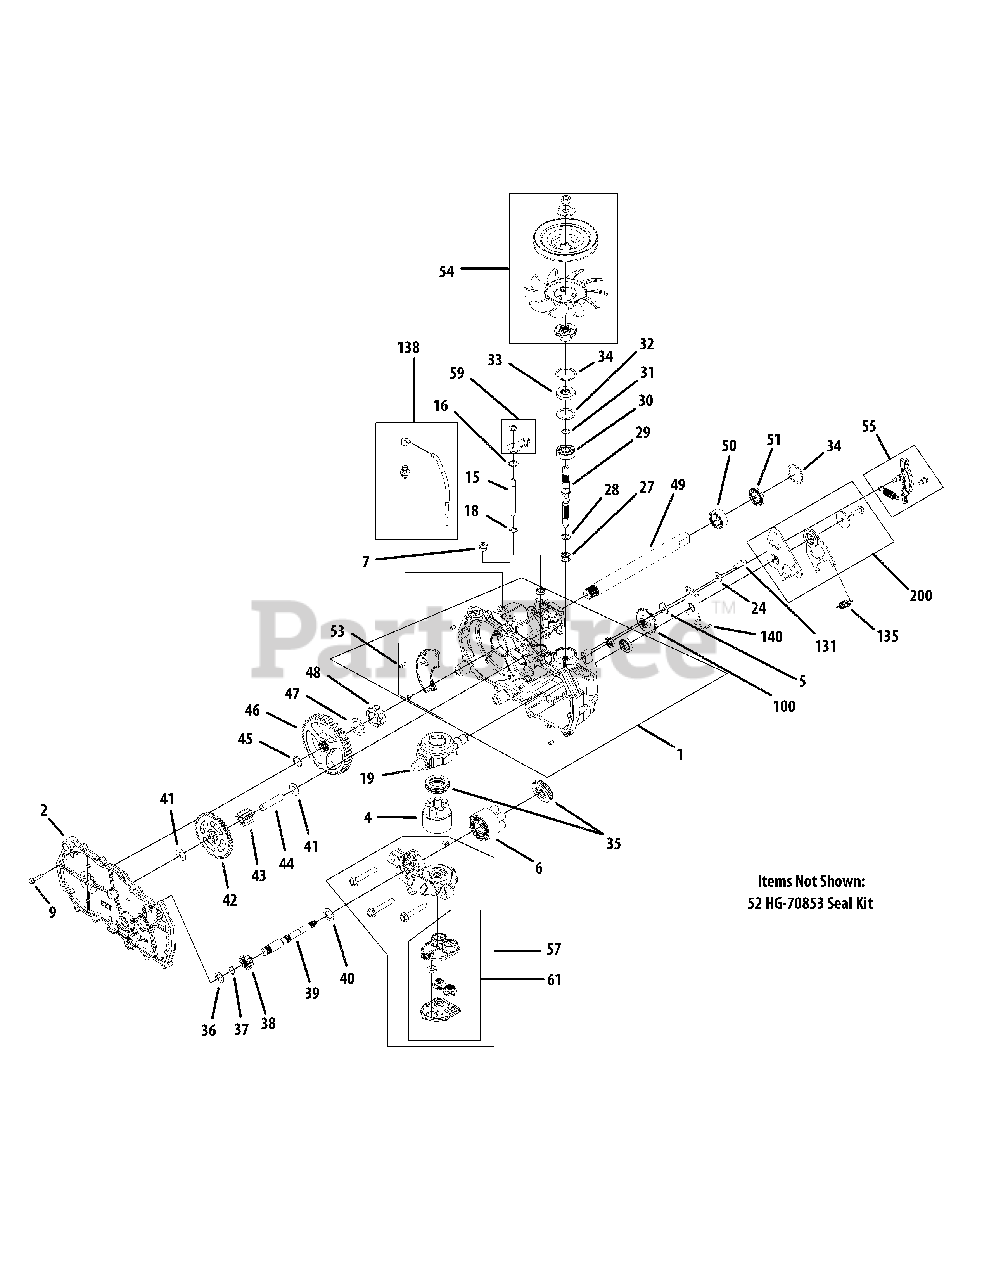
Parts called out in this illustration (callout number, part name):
1	Kit, Housing, Main, LH
2	Kit, Housing, Side, LH
4	Kit, Block, 7 Piston
5	Spacer, .320 x 1.005 x .150
6	Kit, Block, 10cc Cylinder
9	Screw, Hex Washer
15	Rod, Bypass
16	Ring, Ret .375 External
18	Ring, Retaining .375 External
19	Trunnion, Swashplate
24	Washer, .34 x .88 x .06
27	Spring, Block
28	Washer, .59 x .79 x .04
29	Shaft, Input
30	Ball Bearing 17 x 40 x 12
31	Ring, Reatining
32	Washer, 1.23 x 1.57 x .04
33	Seal, Lip 17 x 40 x 7
34	Ring Retaining Internal
35	Thrust Bearing, 30 x 52 x 13
36	Washer, .63 x 1.00 x .05
37	Ring, Reatining, Motor Shaft
38	Gear, 13T Pinion
39	Shaft, Motor
40	Washer, .71 x 1.16 x .04
42	Gear, 10T/48T
43	Gear, 10T Jackshaft
44	Pin, Jackshaft
45	Ring, Spiral Retaining-87
46	Gear, Bull 52T
47	Washer, 1.018 x 1.571 x .105
48	Buahing, Sleeve (Inboard)
49	Shaft, Axle, 1.00 x 11.70 DD
50	Bushing, 1.003 x 1.571 x .625
51	Seal, Lip, TC4, 1.00 x 1.577 x .27
52	Kit, Seals & Rings
53	Kit, Expansion Plate LH
54	Kit, Fan & Pulley
55	Kit, Brake Arm
57	Kit, Center Section LH
59	Kit, Bypass Arm
61	Kit, Filter
100	Disc, Cog Brake
131	Socket Cap Screw, 5/16-24 x 7/8
135	Spring, Extension
138	Kit, Breather
140	Arm, Left Return
200	Kit, RTN Bidirectional
